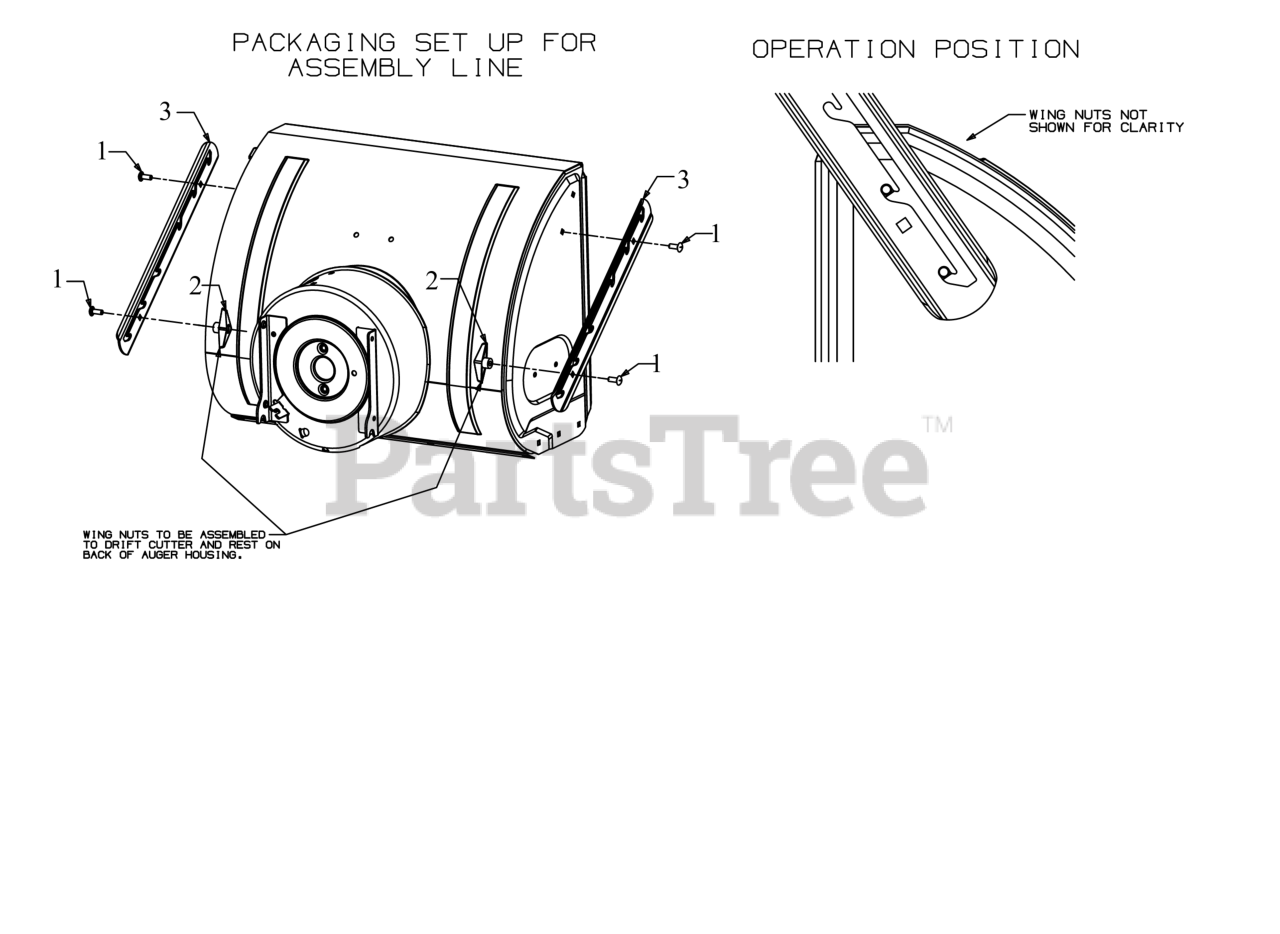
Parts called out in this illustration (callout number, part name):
1	BOLT 5/16-18X .875 GR1
2	WING NUT KNOB
3	19" GUIDE BLADE
